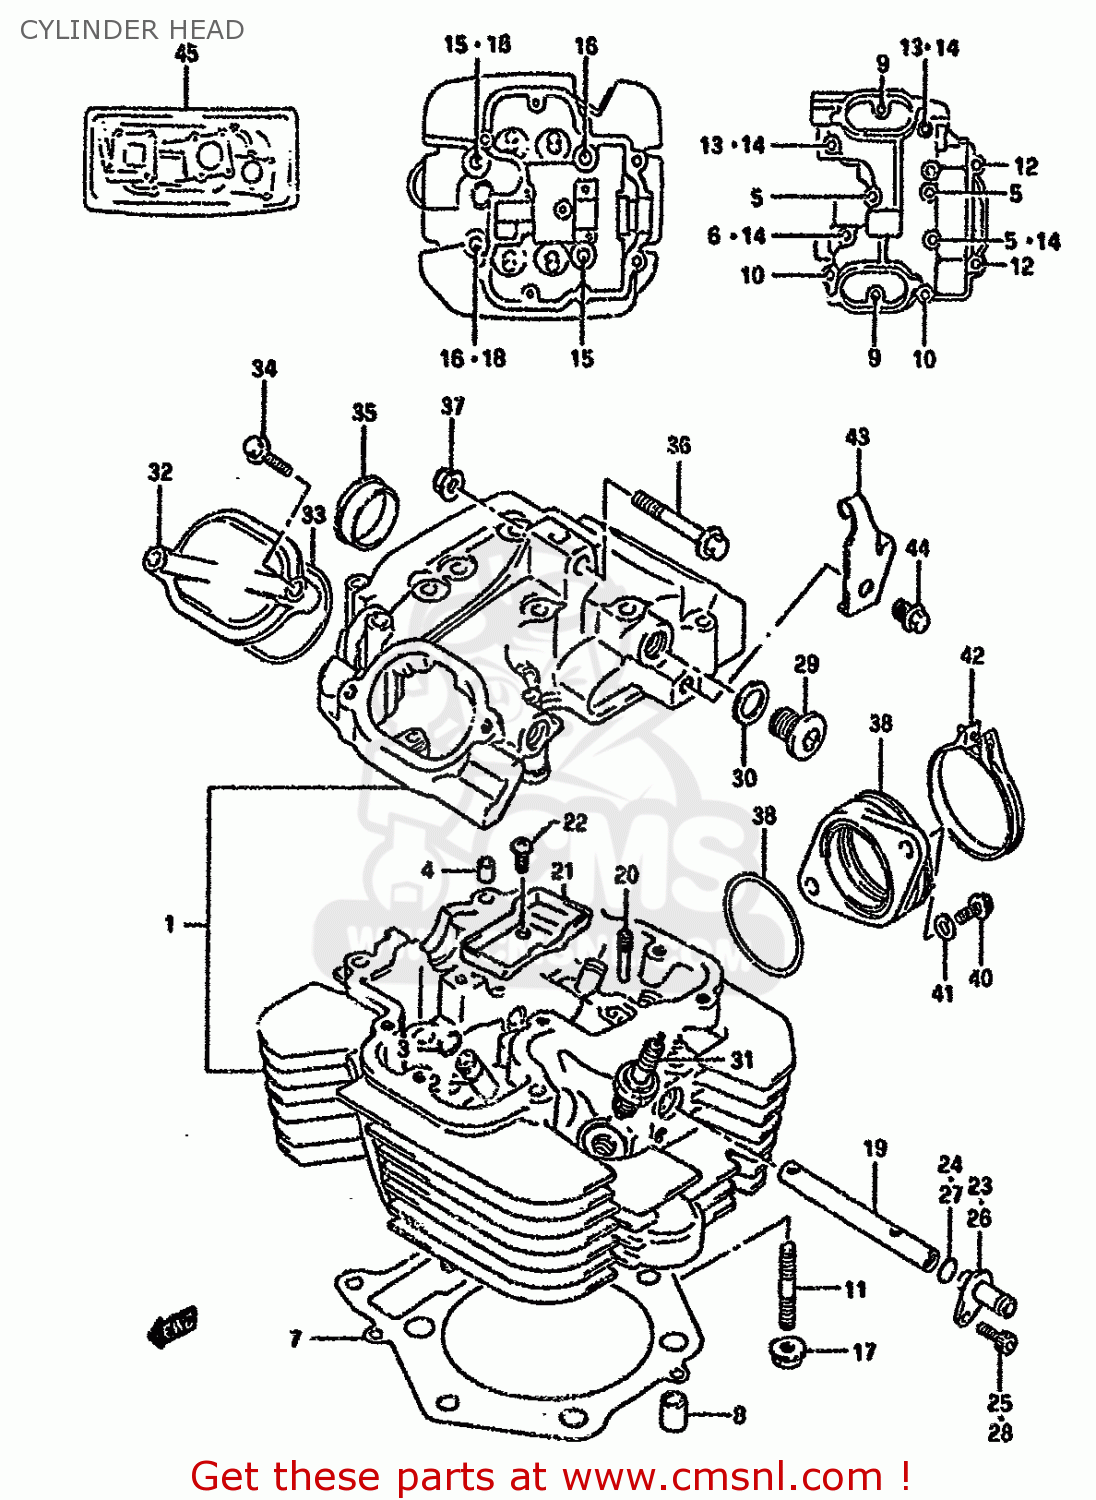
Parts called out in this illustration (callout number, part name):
1	HEAD,CYLINDER
2	GUIDE,VALVE
3	RING,SNAP
4	PIN(6.2X8X11)
5	BOLT
6	BOLT 6X55
7	GASKET,CYLINDER HEAD (NAS)
8	PIN
9	BOLT
10	BOLT
11	BOLT,STUD
12	BOLT(6X130)
13	BOLT
14	GASKET(5.8X13X1.2) (NAS)
15	BOLT(10X190)
16	BOLT(10X215)
17	NUT
18	GASKET(10.5X22X2) (NAS)
19	PIPE,CYLINDER HEAD OIL
20	SCREW (L:19.5)
21	PLATE,CYLINDER HEAD CHAMBER
22	SCREW
23	UNION,CYLINDER HEAD OIL
24	O RING(D:1.3,ID:9.8)
25	BOLT
26	UNION,CYLINDER HEAD OIL
27	O RING,HEAD GASKET
28	BOLT,OIL FILLE
29	PLUG
30	GASKET(14X19.2X2) (NAS)
31	PLUG,SPARK(DPR9EA-9)
32	CAP,INSPECTION
33	O RING(D:2.4,ID:23)
34	BOLT
35	PLUG(OD:30)
36	BOLT 8X53
37	NUT
38	PIPE,INTAKE
39	O RING(D:2.4,ID:45.7)
40	BOLT
41	WASHER
42	CLAMP
43	HOLDER,DECOMP CABLE
44	BOLT 8X16
45	GASKET SET
